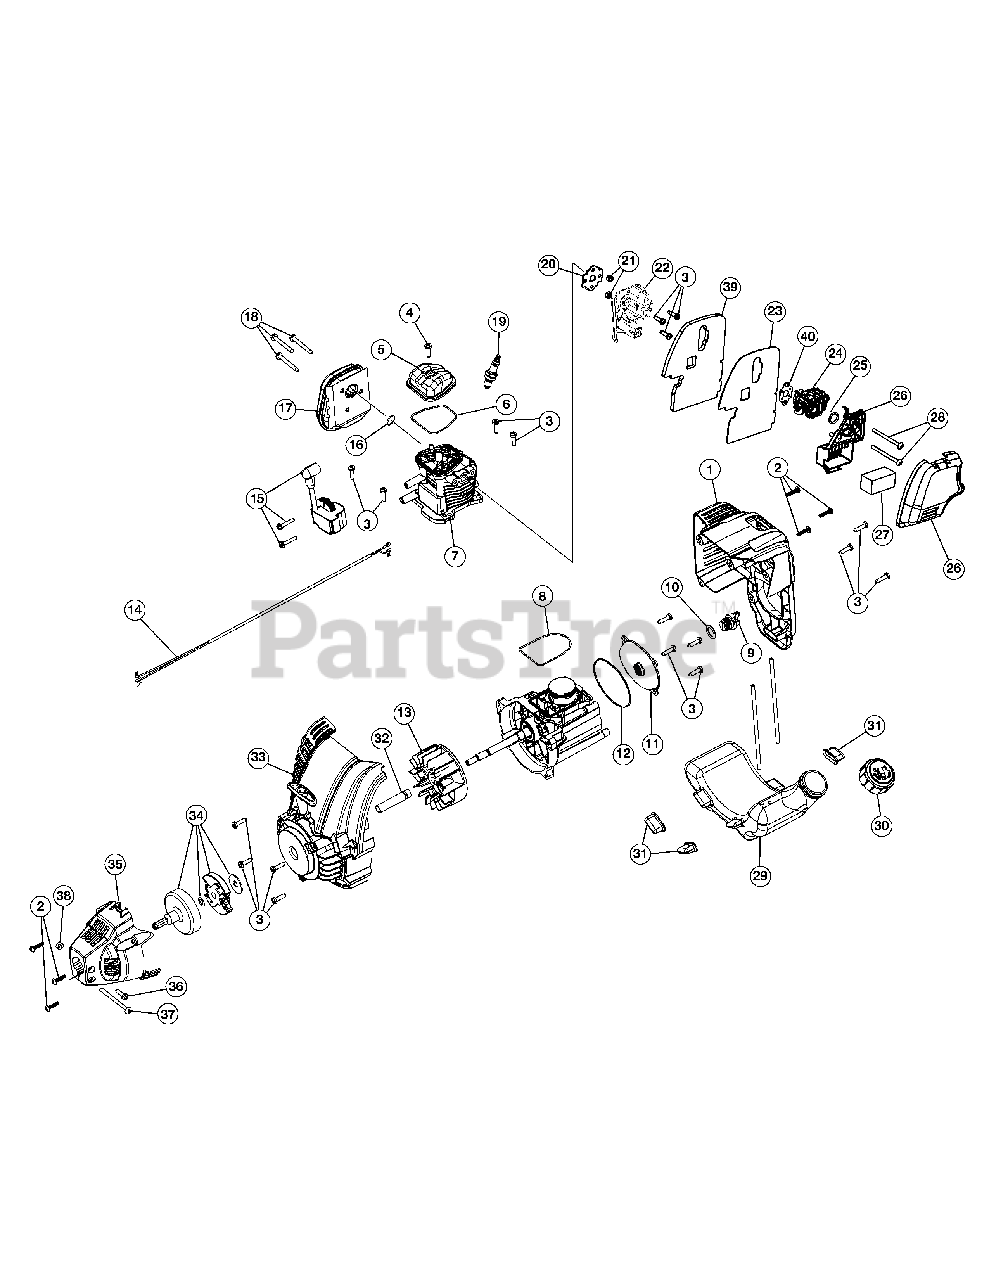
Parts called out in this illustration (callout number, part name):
1	Engine Cover Assembly (Incl. 2 & 3)
2	Cover Screw
3	Housing Screw
4	Rocker Cover Screw
5	Rocker Cover
6	Rocker Cover O-Ring
7	Cylinder Assembly (Incl. 3 - 6 & 8)
8	Cylinder O-Ring
9	Oil Plug (Incl. 10)
10	Oil Plug O-Ring
11	Crankcase Cover
12	Crankcase Cover O-Ring
13	Flywheel Assembly
14	Lead Wires
15	Module Assembly
16	Muffler Gasket
17	Muffler Assembly (Incl. 16 & 18)
18	Muffler Screw
19	Spark Plug
20	Insulator Gasket
23	Carburetor Gasket
24	Carburetor
26	Air Cleaner Cover Assembly (Incl. 27)
27	Air Filter
29	Fuel Tank Assembly w/Fuel Lines (Incl. 30)
31	Fuel Tank Pads
33	Starter Housing Assembly (Incl. 3)
34	Clutch Assembly
35	Clutch Cover (Incl. 2)
36	Anti-Rotation Screw
37	Clamp Screw
39	Heatshield Carb.
